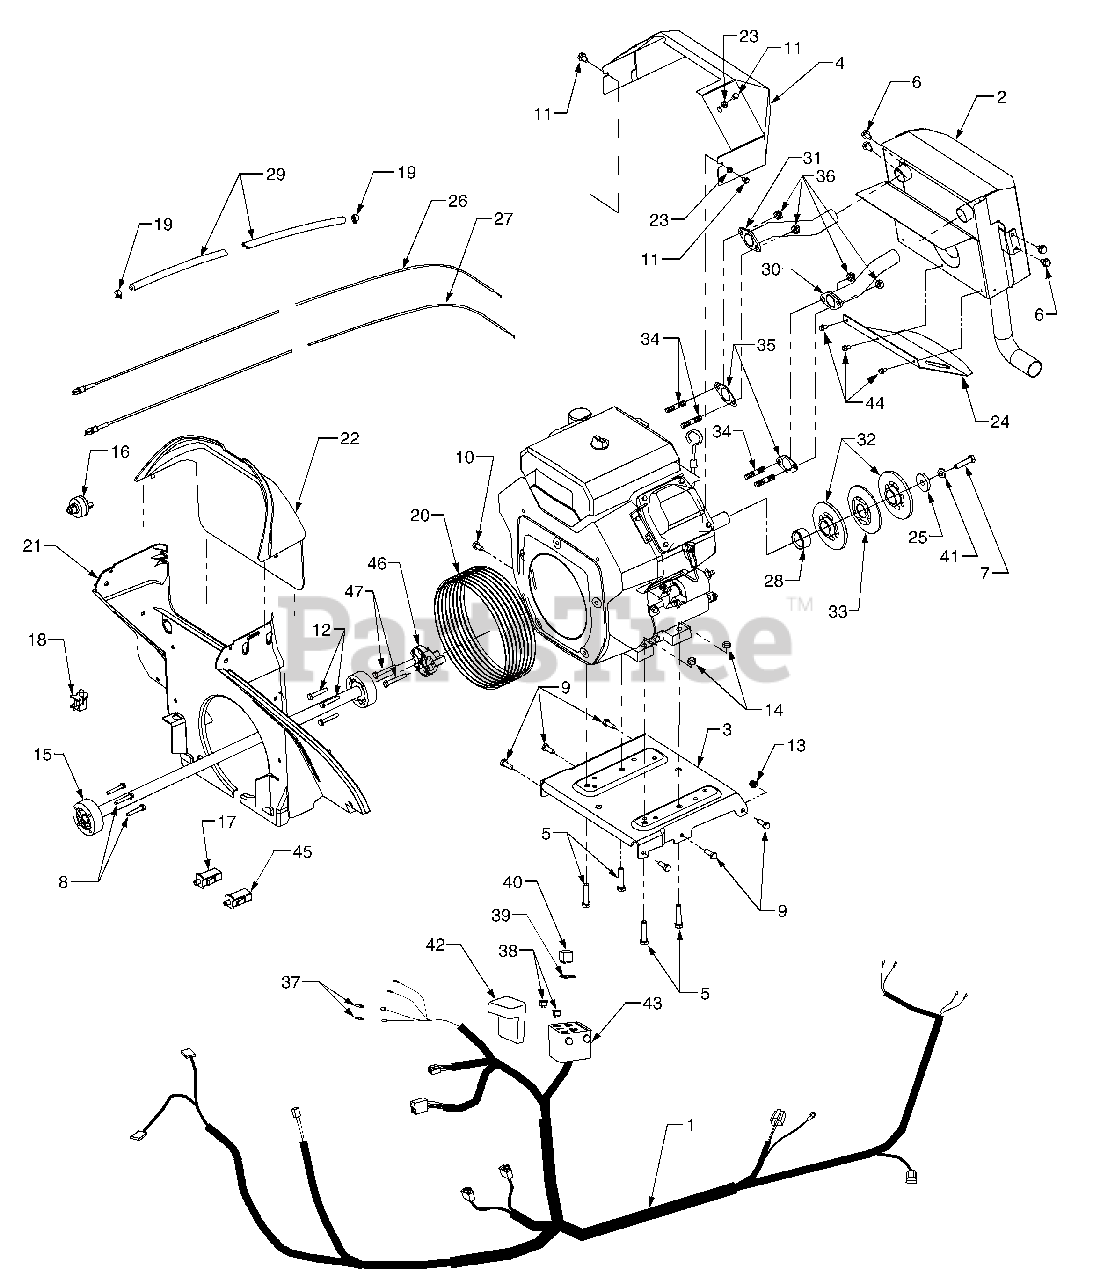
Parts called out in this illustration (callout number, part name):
1	Harness, Wire
1	Tie, Pushmount
1	Clip, Cable
2	Muffler Assembly
3	Plate, Engine Mounting
4	Shield, Muffler Heat
5	Screw, Hex Cap, 3/8-24 x 1.75 GR5
6	Screw, Hex Wash. Hd. Tapp 5/16-18 x .5
7	Screw, Hex Cap, 7/16-20 x 1.5 GR5
8	Screw, Hex Cap Lock 1/4-20 x 1.25 GR5
9	Screw, Hex Cap, 5/16-18 x .875 GR5
10	Screw, Hex Cap, M8 - 1.25 x 16MM GR5
11	Screw, Hex Cap, M6 - 1.0 x 10MM
12	Screw, Hex Cap, Lock 1/4-20 x 1.62 GR5
13	Nut, Hex Insert Lock, 5/16-18
14	Nut, Hex Lock, 3/8-24
15	Shaft, Drive, 27.125 Long
16	Switch, Key w/Ground
17	Switch, Plunger
18	Switch, Snap Mount
19	Clamp, Hose
20	Boot, Intake
21	Baffle, Lower Air
22	Baffle, Upper Air
23	Washer, Flat, .281 x .50 x .06
24	Shield, Lower Exhaust
25	Washer, Flat, .417 x 1.5 x .225
26	Cable, Throttle Control
27	Cable, Choke Control
28	Spacer, Crankshaft
29	Hose, Fuel Line
30	Pipe, Exhaust RH
31	Pipe, Exhaust LH
32	Pulley Half
33	Pulley, Center
34	Stud, M8 - 1.25 x 33MM
35	Gasket, Exhaust
36	Nut, Hex, M8 x 1.25
37	Bulb, Indicator
38	Fuse, 25 Amp
39	Gasket, Silicone
40	Relay, PTO
41	Washer, Lock, 7/16
42	Cover, Fuse Box
43	Box, Fuse
44	Screw, Hex Wash. Hd. Tapp, #12-24 x .38
45	Switch, Plunger
46	Adapter, Drive Shaft
47	Screw, Hex Flange, M10 x 1.5 x 90
